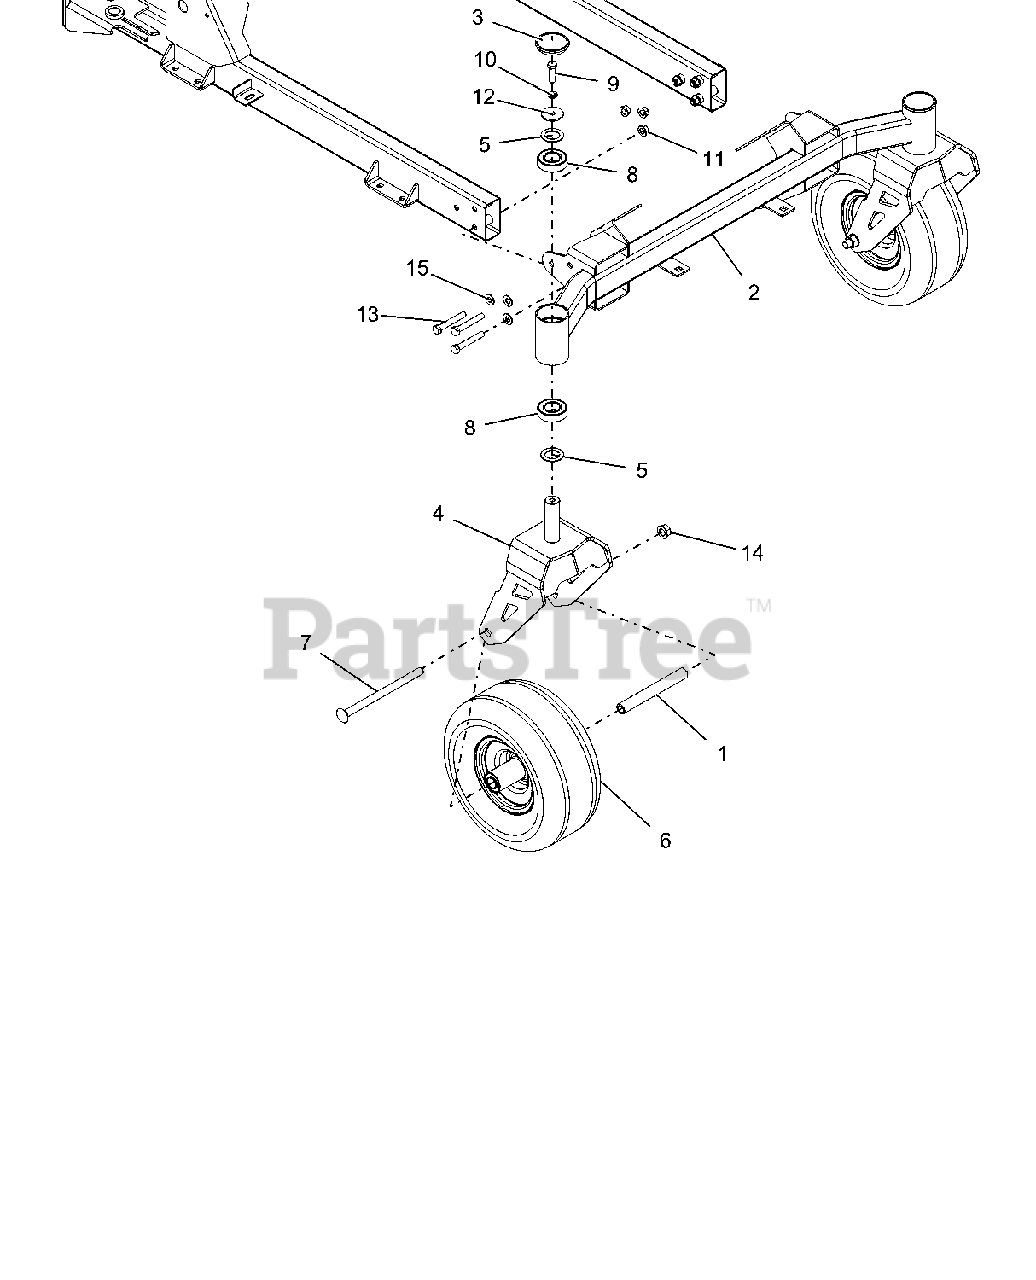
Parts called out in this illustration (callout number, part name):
1	SPCR, FRONT WHEEL (WIDE)
2	WLDMT, AXLE FRONT
3	CAP, DUST
4	WLDMT, CASTER FORK-XL (RED)
5	WSHR, HRD THRS 1.007X1.542X.062
6	TIRE/WHEEL, 11X6-5
7	BLT-RDHDSQNK .50-13X7.50 G5 Y
8	BRG-BALL 1.00X2.00X.56
9	BLT-HEX .38-16X1.25 GR5 YWZC
10	WSHR-LK .38X.094 REG YWZC
11	NUT, LK-TOP-FLG .38-16 GRG YWZC
12	WSHR-FL-STL .380X1.50X.125 YWZC
13	BLT-HEX .38-16X2.50 GR8 YWZC
14	NUT, LK-TOP-FLG .50-13 YWZC
15	WSHR-HDND .406X.812X.075
